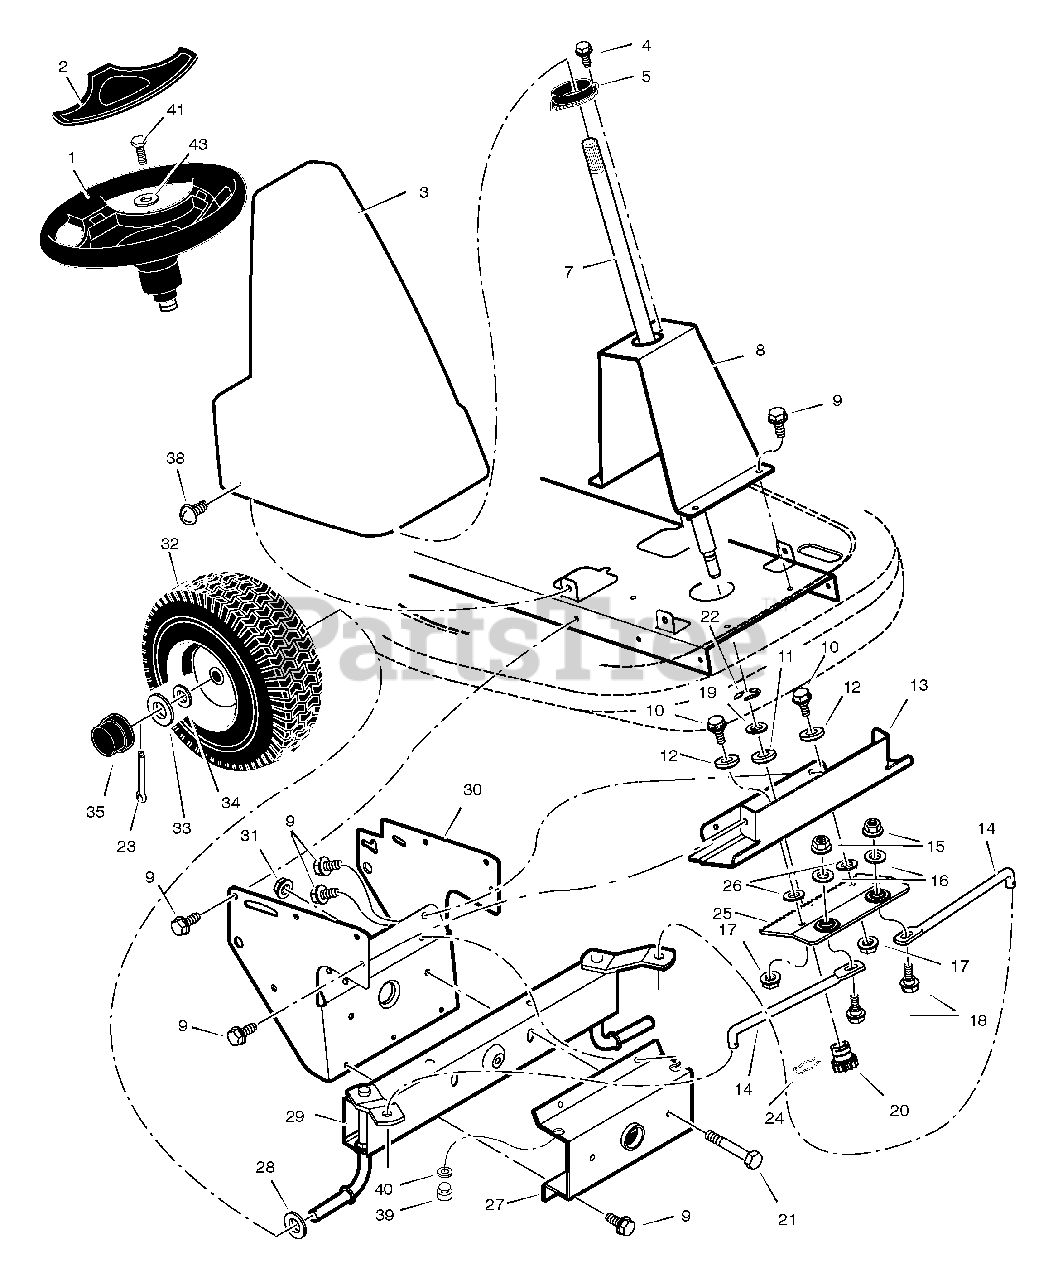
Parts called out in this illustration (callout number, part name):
1	Wheel, Steering
2	Cover, Steering Wheel
3	Console, High (Black)
4	Screw
5	Bearing, Upper Steering
7	Shaft, Steering
8	Support, Steering
10	Bolt, Shoulder
11	Bearing, Lower Steering
13	Plate, Gear Mounting
14	Link, Drag
15	Nut, Flange
16	Washer
17	Nut, Flange
18	Bolt, Hex
19	WASHER, 1-1.3 16G FLT
20	Gear, Pinion
21	Bolt, Hex
22	E-Ring, Retainer
23	Pin, Cotter
24	Retainer, Spring
25	Rack, Steering
27	Bracket, Axle Front
28	Washer
29	Axle & Spindle Assembly
30	Bracket, Support
31	Nut, Flange
32	Wheel, Front
34	Washer
35	Cap, Hub
38	Screw
39	Bumper, Rubber
41	Screw, Hex
43	Washer
